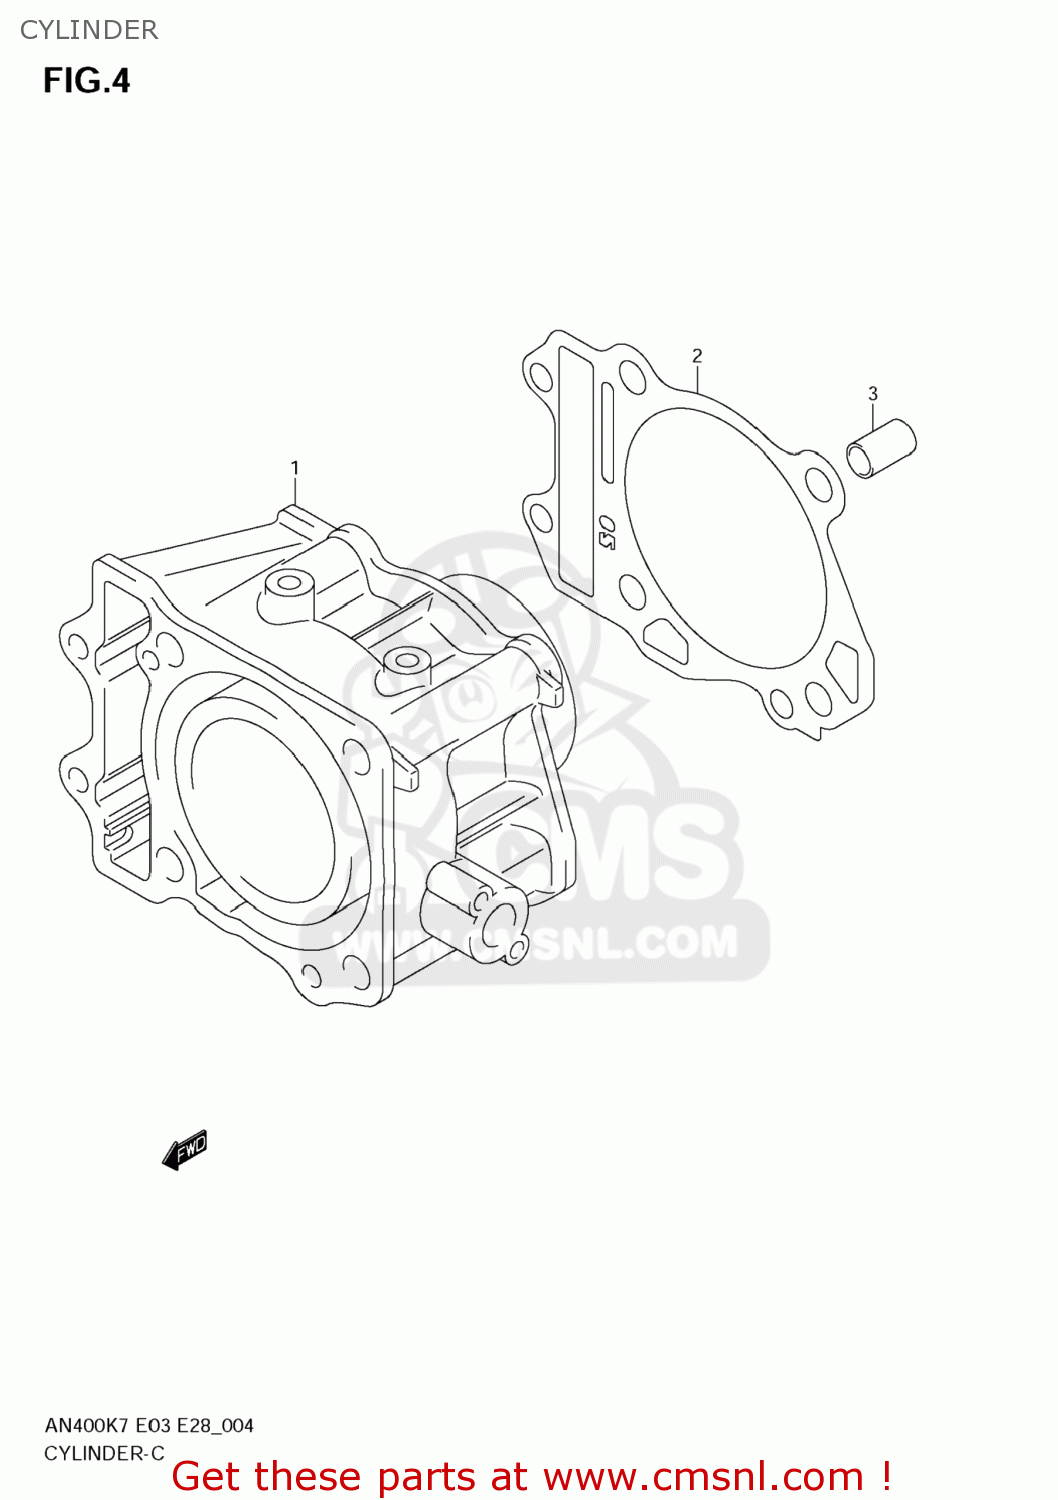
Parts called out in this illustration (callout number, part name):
1	CYLINDER
2	GASKET,CYLINDER (NAS)
3	PIN
